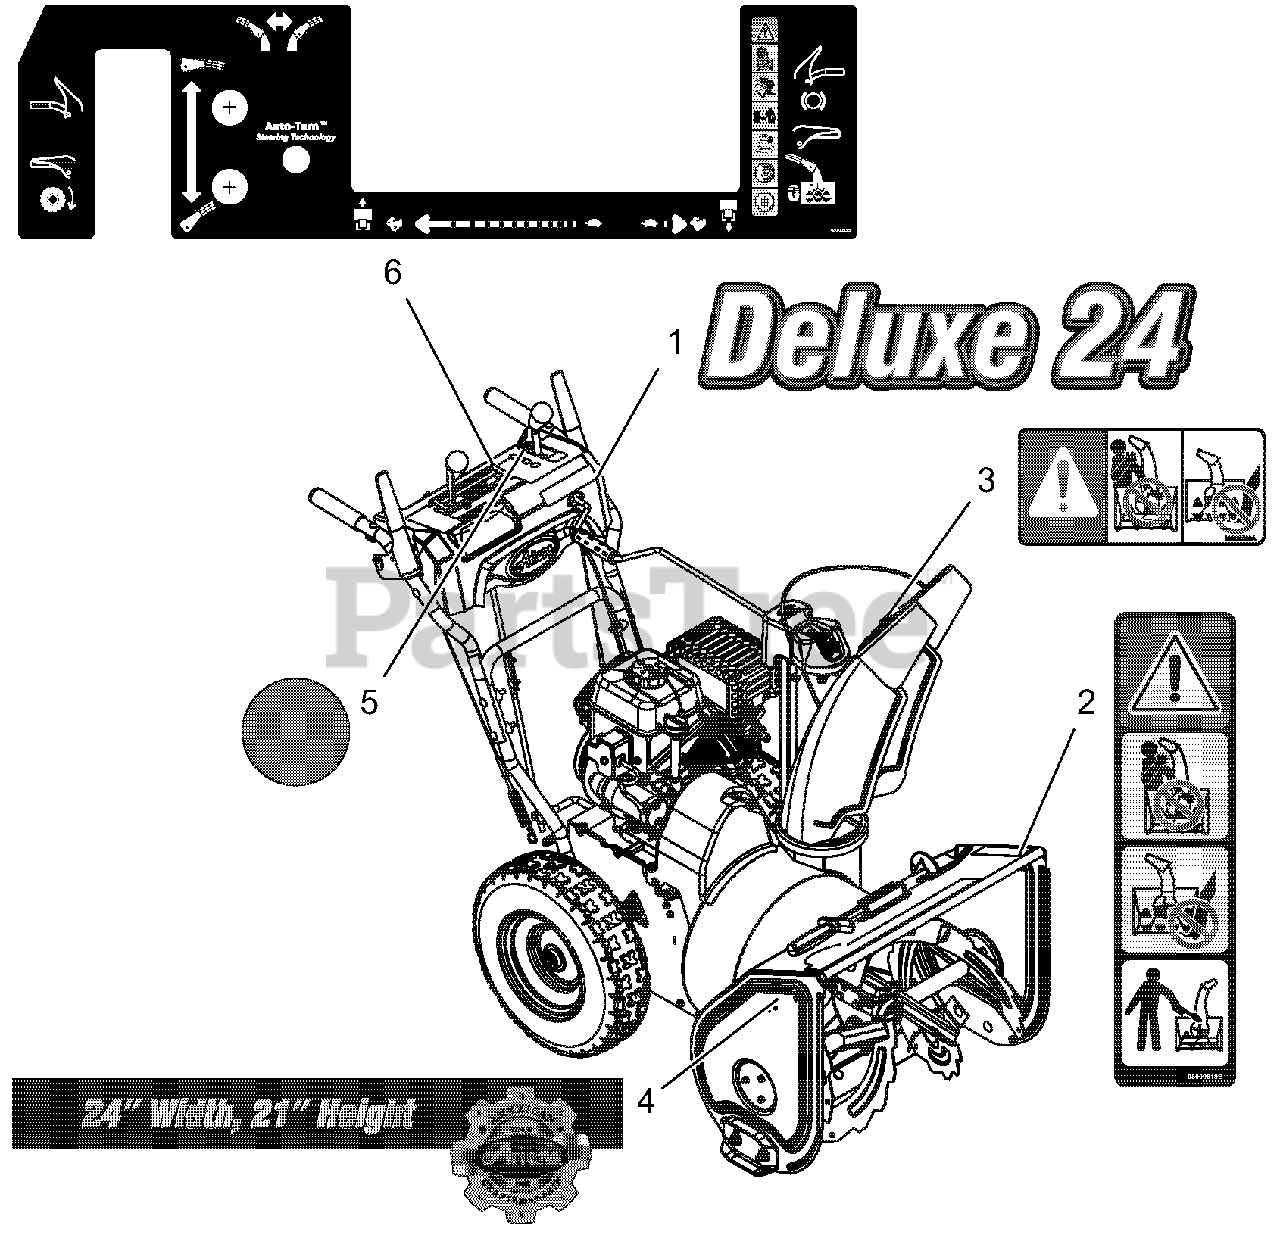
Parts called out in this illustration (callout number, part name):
1	DECAL,ST24 DELUXE-COMPACT DASH
2	DECAL, DANGER - ROTATING PARTS
3	DECAL, DANGER
5	DECAL,AUTODIFFERENTIAL
6	DECAL,CONTROL-SML,AT,ID
